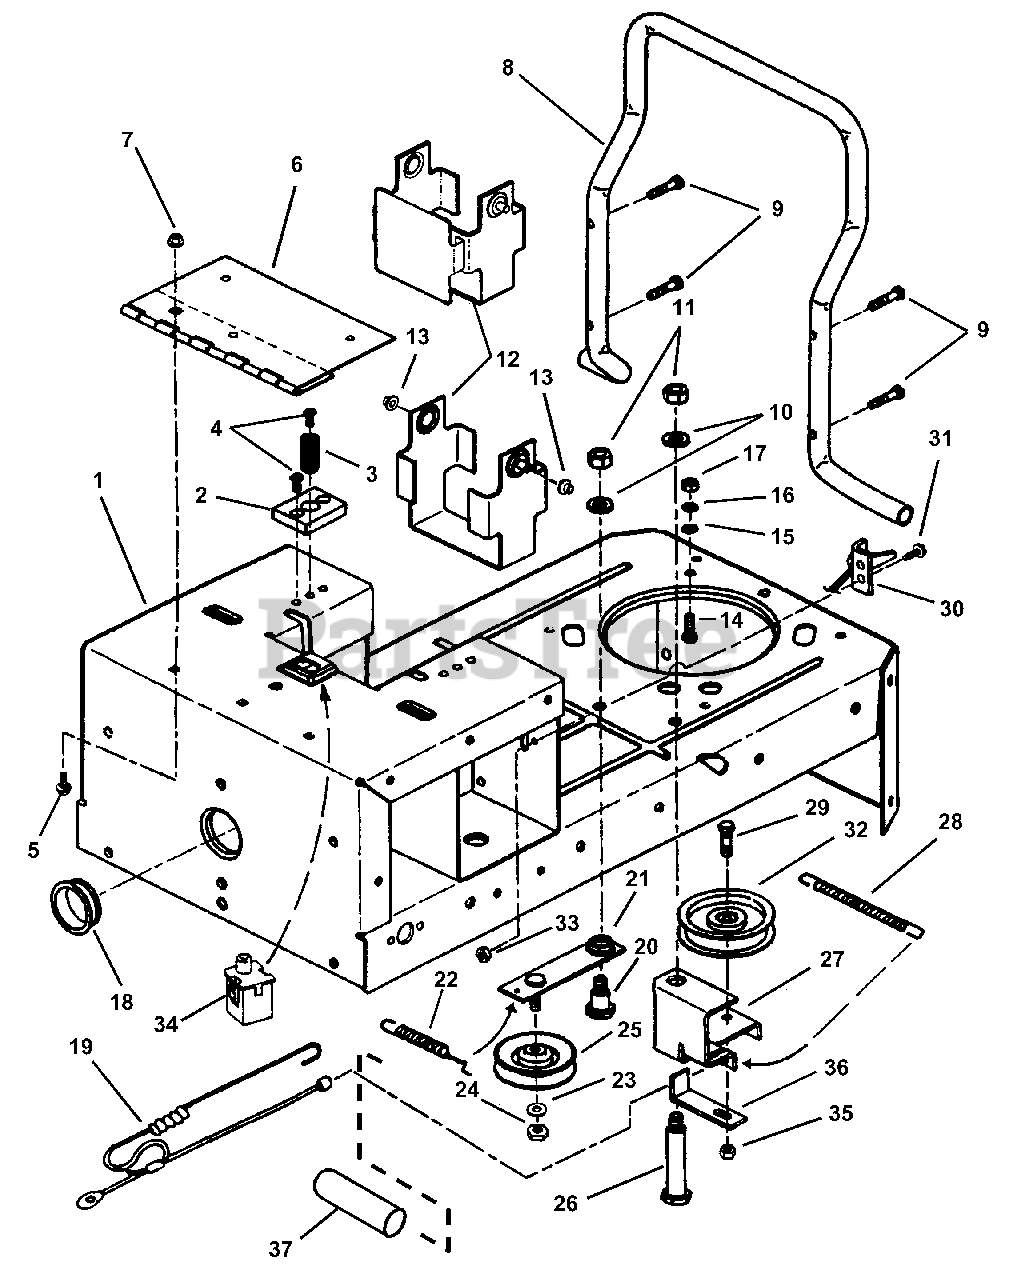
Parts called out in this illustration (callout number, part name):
1	FRAME, Rear
2	CUSHION, Seat Support
3	SPRING, Seat Support
4	SCREW, 1/4-20 x 5/8" Pan Head, Self-Tapping
5	BOLT, 5/16-18 x 1/2" Carriage, Grade 5
6	HINGE, Seat
7	NUT, 5/16-18 Hex Flange Lock, Grade 5
8	BUMPER, Rear
9	SCREW, 5/16-18 x 1-1/2" Hex Washer Head, Self-Tapping
10	WASHER, 1/2" Flat
11	NUT, 1/2-13 Hex, Grade B
12	BRACKET, Battery
13	BUSHING
14	SCREW, 5/16-24 x 1" Hex Head Cap
15	RETAINER, 5/16 Bolt
16	WASHER, 5/16 Split Lock
17	NUT, 5/16-24 Hex, Grade 5
18	GROMMET
19	CABLE, Brake/Clutch
20	BOLT, 1/2-13 x 5/8" Thread, .75 x .788 Shoulder
21	IDLER ARM, Primary
22	SPRING, Clutch/Brake (5" long)
23	WASHER, 3/8" Flat
24	NUT, 3/8-16 Hex Center Lock, Grade 5
25	PULLEY, Idler 3.30 Dia.
26	BOLT, 1/2-13 x 5/8" Thread, .75 x 3.23 Shoulder
27	BRACKET, Hydraulic Idler
28	SPRING, Drive Idler (3/4" x 10" long)
29	SCREW, 5/16-18 x 1" Hex Head Cap, Grade 5
30	CABLE, Hydro Release Valve
31	SCREW, #10-32 x 5/8" Hex Washer Head, Machine
32	IDLER, 4.12 Flat
33	NUT, #10-32 Hex Nyloc
34	SWITCH, Seat
35	NUT, 5/16-18 Hex Center Lock
36	GUIDE, Belt
37	COVER, Spring
